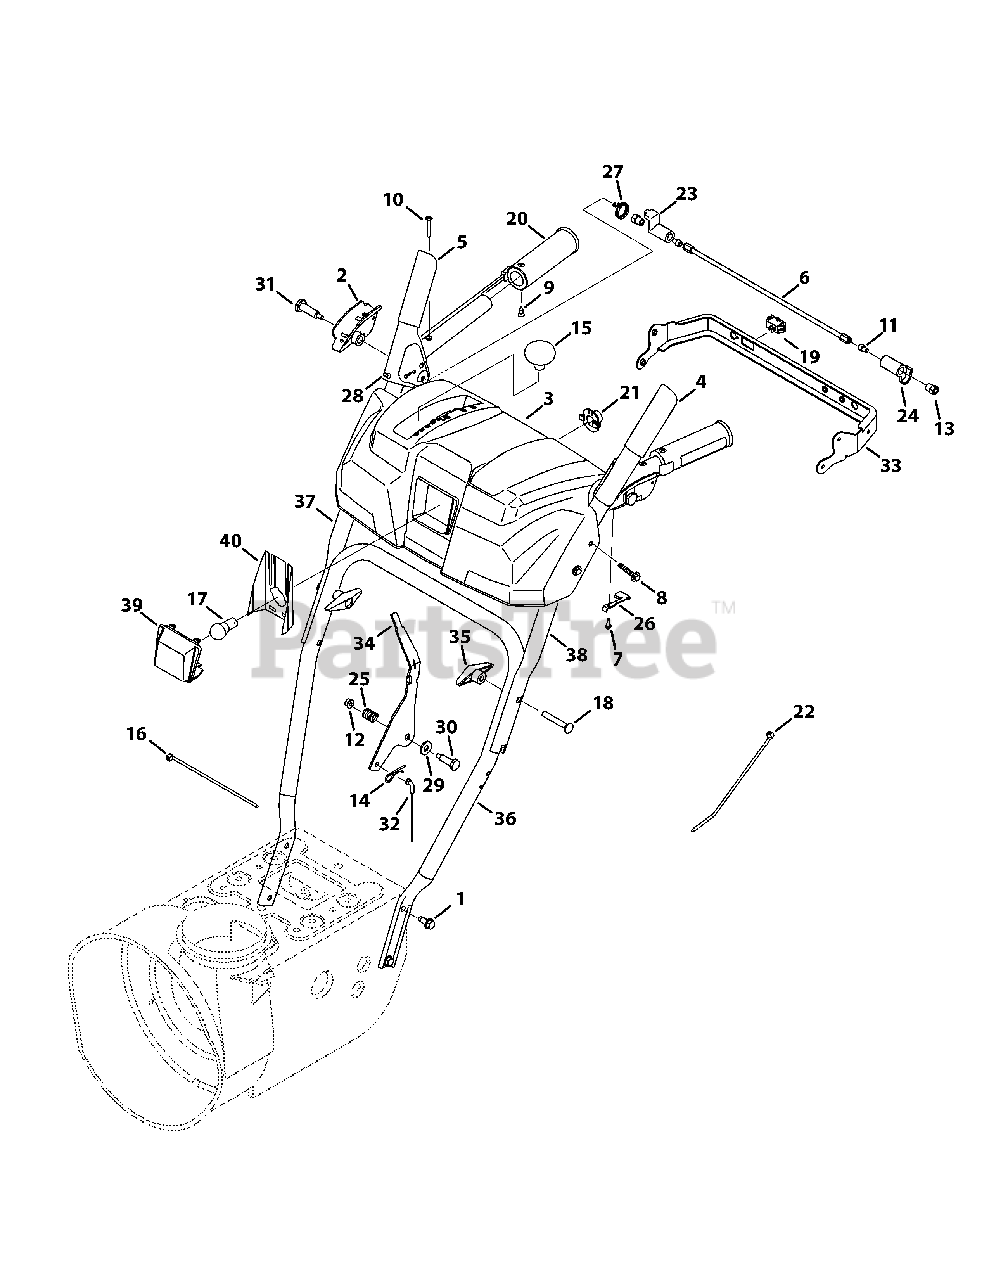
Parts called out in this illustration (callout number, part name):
1	Screw, Taptite, 5/16-18 x .750
2	Clutch Lock, RH
2	Clutch Lock, LH
3	Handle Panel w/o Light
4	Auger Engage
5	Drive Engage
7	Screw, Plastite, 8-16 x .50
8	Screw, Taptite, 1/4-20 x 1.625
9	Screw, 10-16 x 0.625
10	Screw, 10-24 x 1.375
11	Screw, 1/4-20 x .50
12	Nut, Flange Lock, 1/4-20
13	Nut, Hex, 1/4-20
14	Click Pin, .092 x 1.64
15	Shift Knob
16	Cable Tie, 7"
17	Lamp, 12.8V
18	Screw, Carriage, 5/16-48 x 2.25
19	Heated Grip Switch
20	Heated Grip
21	Lamp Socket
22	Cable Tie, Push Mount
23	Plate, Lock
24	Cam, Clutch Lock
25	Compression Spring, .39 x .60 x .88
26	Clutch Lock Spring
27	Torsion Spring, 0.8156 x .3038
28	Rubber Bumper
29	Washer, Flat, .385 x .87
30	Screw, Shield, .374 x 1.05
31	Screw, Shoulder, .437 x 1.345 x 1/4-20
32	Speed Selector Cable
33	Panel Bracket
34	Shift Lever
35	Wing Knob
36	Lower Handle
37	Upper RH Handle
38	Upper LH Handle
39	Lens Panel, Troy-Bilt
40	Lens Label, Troy-Bilt
